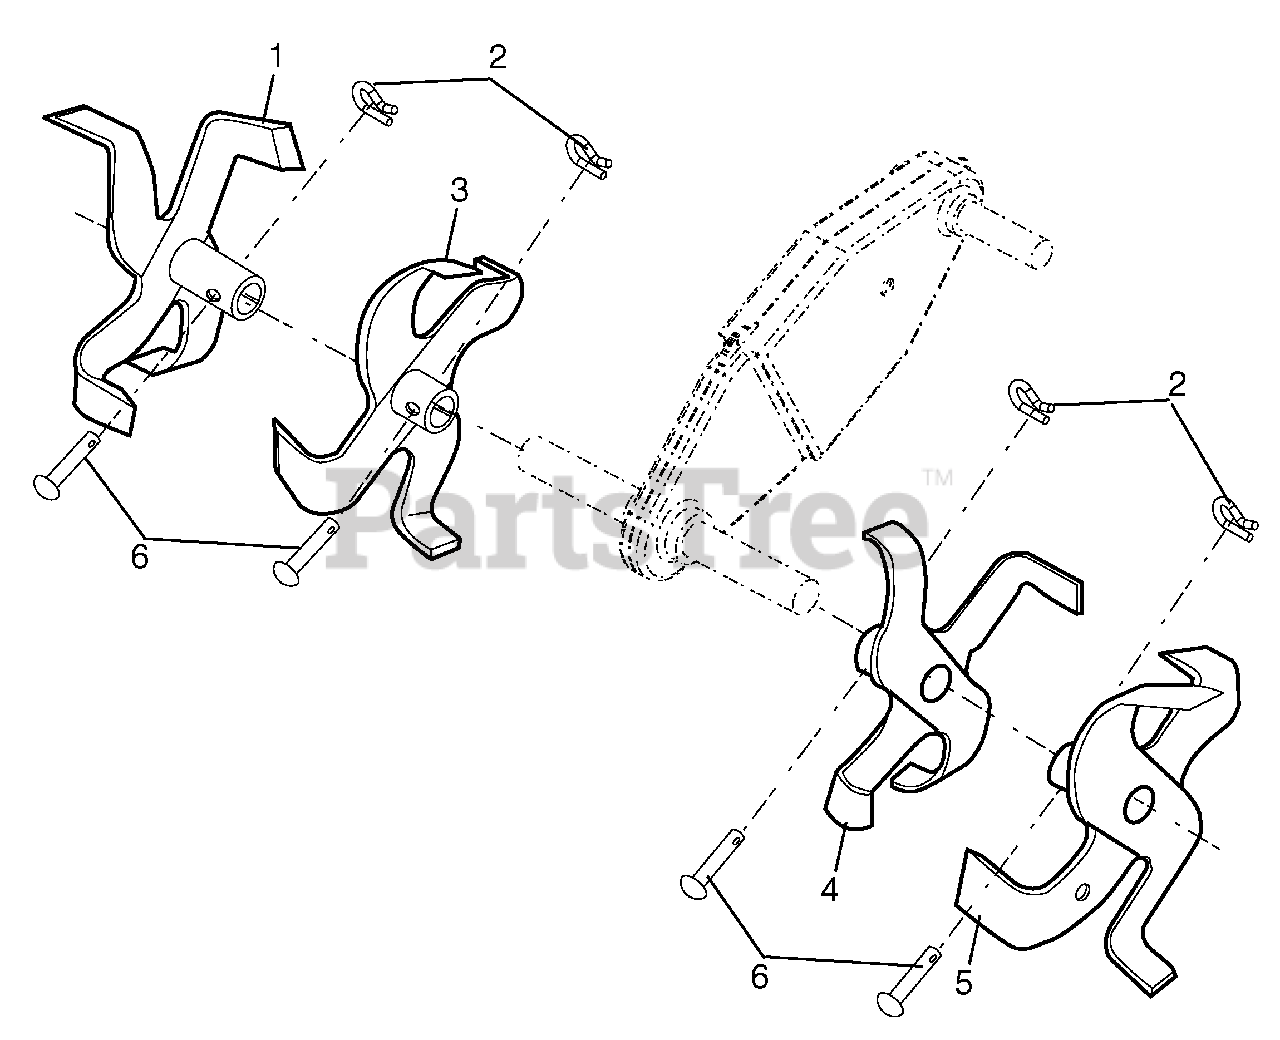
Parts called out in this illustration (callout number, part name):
1	Tine, Outer, R.H.
2	Retainer, Spring
3	Tine, Inner, R.H.
4	Tine, Inner, L.H.
5	Tine, Outer, L.H.
6	Pin, Clevis
